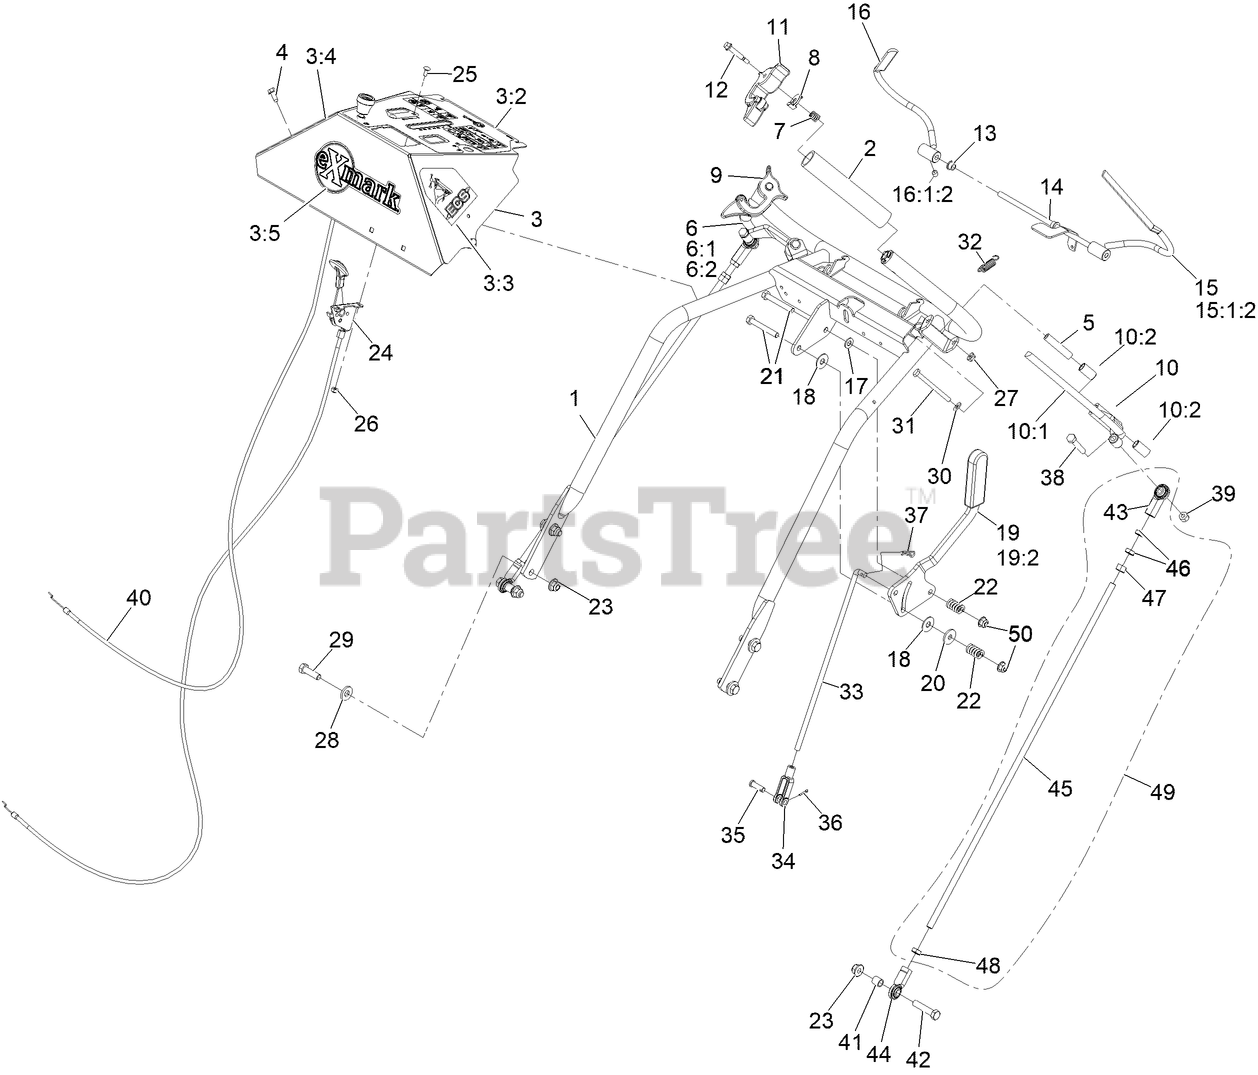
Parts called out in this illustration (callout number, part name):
1	WELD, HANDLE
2	GRIP-BAR, HANDLE
3	ASM, CONSOLE W/ DECALS
3:2	DECAL-CONSOLE
3:3	DECAL,LH ECS INSTRUCTION
3:4	DECAL,RH ECS INSTRUCTION
3:5	DECAL, EXMARK LOGO
4	SCREW-HWH
5	BUSHING-LEVER, DRIVE
6	DRIVE LEVER-ASM, RH
6:1	WLD,RH DRIVE LEVER
6:2	BUSHING, SLEEVE
7	SPRING-TANK, FUEL
8	LATCH, ECS
9	ASM,LATCH RH THUMB
10	DRIVE LEVER-ASM, LH
10:1	WLD,LH DRIVE LEVER
10:2	BUSHING, SLEEVE
11	ASM,LATCH LH THUMB
12	SCREW-SHOULDER
13	BUSHING-NYLON
14	WLD,OPC LEVER AXLE
15	WLD,LH OPC LEVER
15:1:2	SCREW-SET
16	WLD,RH OPC LEVER
16:1:2	SCREW-SET
17	WASHER-PLAIN
19	LEVER, SHIFT W/GRIP
19:2	GRIP-HANDLE, STEERING
20	WASHER-FRICTION
21	SCREW-HH
22	SPRING-COMPRESSION
23	NUT-HF, NI
24	CONTROL-THROTTLE
25	BOLT-CARR
26	NUT-LOCK, NI
28	WASHER-BELLEVILLE
29	SCREW-HH
30	WASHER-FLAT
31	SCREW-HH
32	SPRING-EXTENSION
33	ROD,SPEED CONTROL
34	YOKE-ADJUSTABLE
35	PIN-CLEVIS
36	PIN-COTTER
37	PIN-COTTER
38	SCREW-HH
39	NUT-LOCK, NI
40	CABLE, CHOKE
41	SPACER-TUBE, PUMP LINK
42	SCREW-HH
43	JOINT-BALL, END
44	JOINT-BALL END, LH
45	LINK,DRIVE (PLTD)
46	NUT-HJ
47	NUT-HEX
48	NUT-HEX JAM, LH
49	DRIVE LINK ASM
50	NUT-HF, NI
